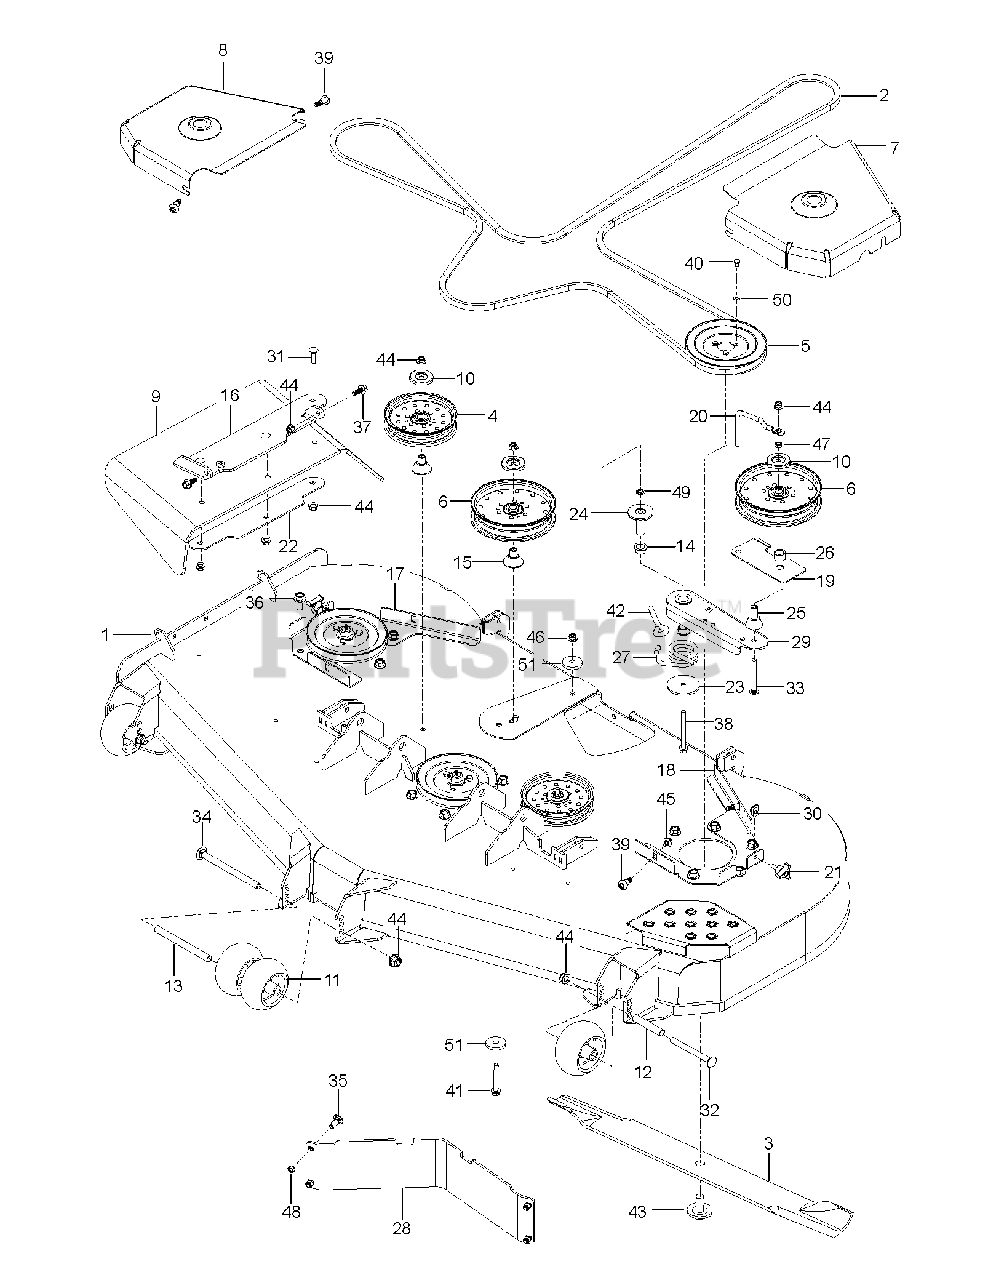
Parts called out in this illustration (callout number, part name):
1	DECK.SVC.W/DECALS.72".7GA.ORG
2	BELT.5V.201
3	BLADE - HEAVY DUTY 21"
4	PULLEY - 7.50
5	PULLEY - IDLER 7"
6	PULLEY IDLER, 6" NARROW
7	COVER.PULLEY.LH.PNT
8	COVER.PULLEY.RH.PNT
9	Discharge Chute
10	DUST SHIELD
11	ROLLER, GAUGE .635 BORN
12	TUBE, ROLLER AXLE
13	TUBE, ROLLER AXLE LONG
14	BEARING, FLANGE
15	BEARING, IDLER ARM
16	BRACKET.CHUTE.ORG
17	BRACKET.PULLEY.COVER.LH.PNT
18	BRACKET.PULLEY.COVER.RH.PNT
19	Lower Guard Plate Belt, Pnt 431
20	KEEPER KEEPER., BELT
21	KNOB W/STUD
22	PLATE.BACKING.DISCHARGE.CHT.BK
23	PLATE.SPRING.RETAINER
24	SHAFT.MOUNT.ARM.IDLER
25	Idler Spacer
26	Pulley Intermediate Spacer
27	SPRING.TORSION.DECK.IDLER.TMSN
28	BAFFLE, DIVERTER 72" BLACK
29	ARM.PNT.WLD.TENSIONR.IDLER.BLK
30	U-CLIP 5/16-18 NUT RETAINER
31	BOLT.3/8-14X1.25
32	RHSNB 1/2-13 X 4.75 GR5 ZD
33	BOLT.RDHD SQNK 3/8-16 X 3-1/2
34	RHSNB 1/2-13 X 8 GR5 ZD
35	1/4-20X3/4 CARR BLT
36	HHFS 1/2-13 X 1 GR5 ZD
37	HHFS 3/8-16 X 1 GRD 5 ZD
38	HHFS 3/8-16 X 4 GR5 ZD
39	SCREW.SHLDR.3/8 X 1/2.5/16-18
40	HCS 5/16-18 X 1/2 GR 5 ZD
41	HHFS 3/8-16 X 2-3/4 GR5 ZD
42	EYE BOLT, 3/8 X 4"
43	BLADE BOLT/WASHER
44	NUT 3/8-16 HEX FLG NYLOC ZD
45	5/16-18 NYLOC FLANGE NUT
46	NUT, 1/2-13 HEX FLG NYLOC ZD
47	NUT 3/8-16 HEX JAM
48	RP_NUT 1/4-20 NYLOC
49	NUT 3/8 PALNUT RTNG BLK PHOS
50	WASH 5/16 DISC SPRING ZD
51	SPINDLE WASHER
